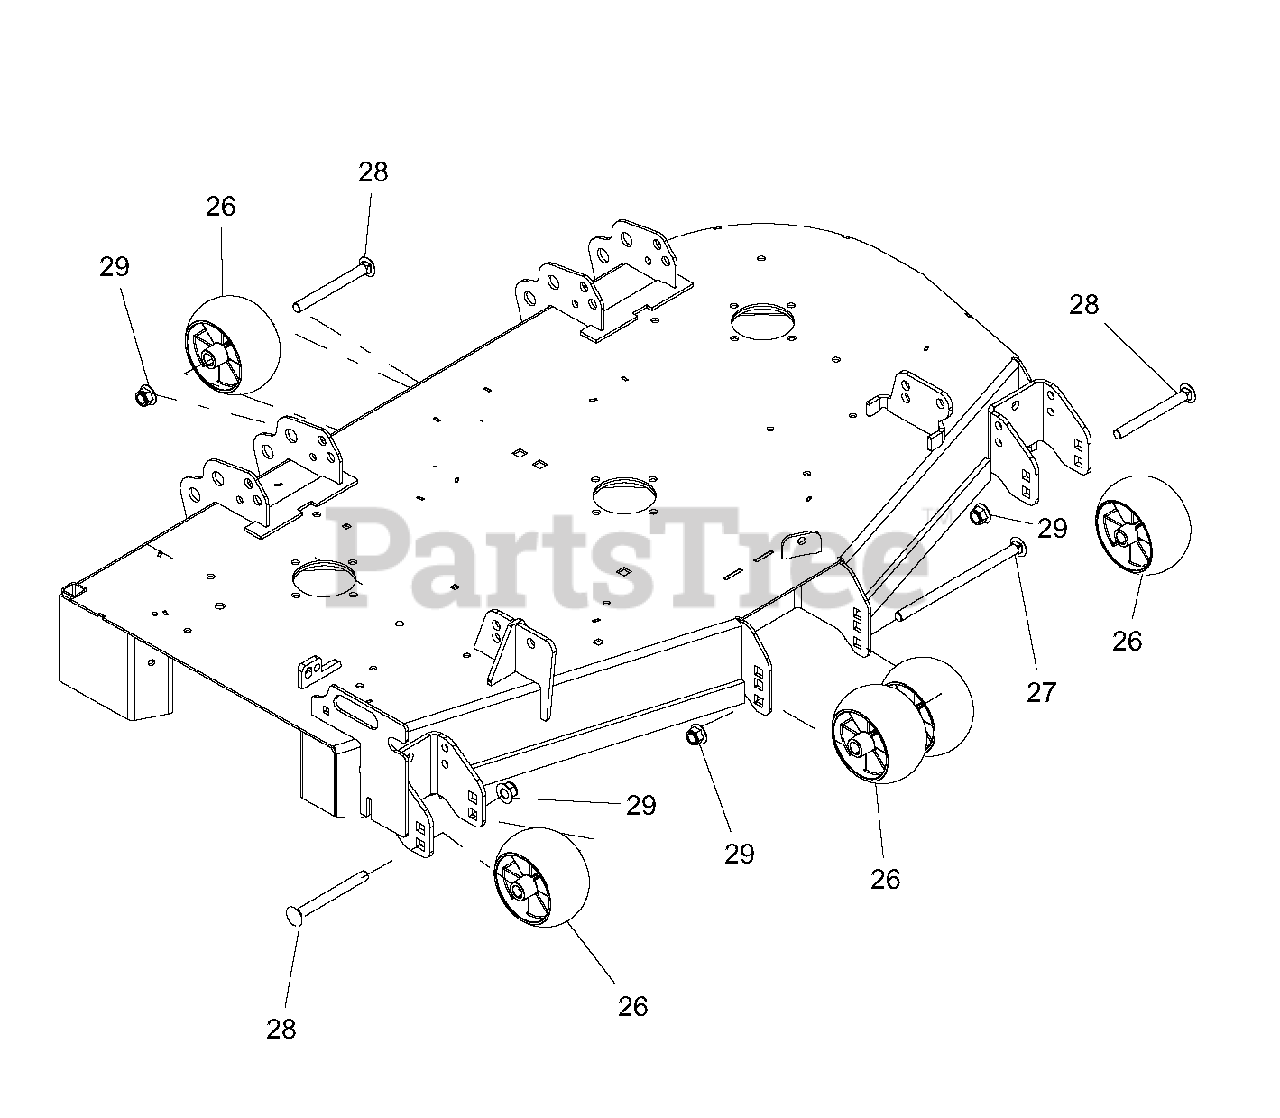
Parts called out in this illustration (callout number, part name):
26	ANTI-SCALP WHEEL - 5X3 CTR
27	@BLT-RDHDSQNK .50-13X8.50 Y
28	@BLT-RDHDSQNK .50-13X4.50 G5 YWZC
29	NUT-LK-NYL-FLG .50-13 YWZC
